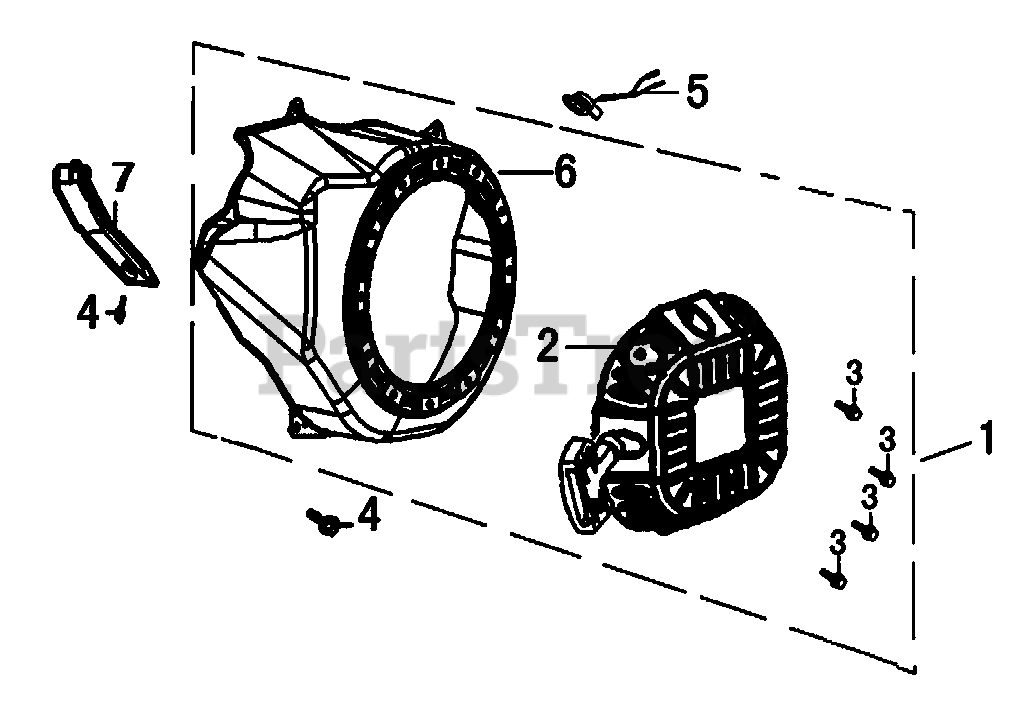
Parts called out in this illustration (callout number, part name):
1	RECOIL STARTER, W/HSNG
2	STARTER ASSY.
3	BOLT, FLANGE 6X8
4	BOLT, FLANGE 6X12
5	SWITCH ASSY., ENGINE STOP
6	HOUSING, FAN BLOWER
